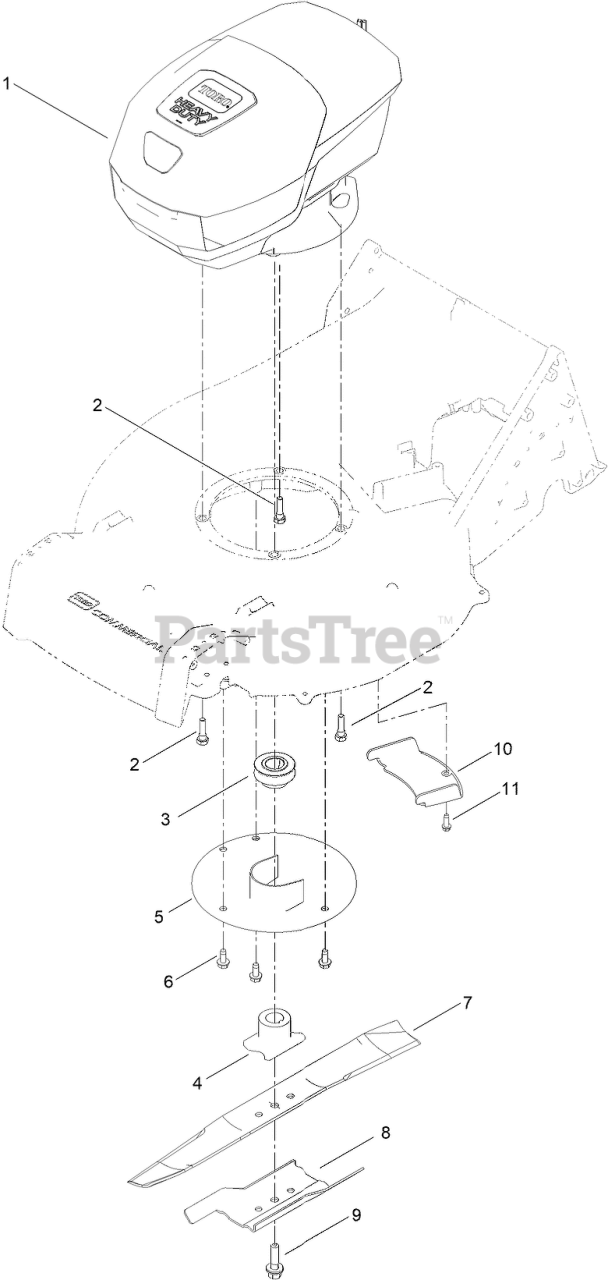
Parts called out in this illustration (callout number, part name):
1	MOTOR MODULE
2	SCREW-TAPTITE
3	PULLEY-DRIVER
4	DRIVER-BLADE
5	PROTECTOR-CRANKSHAFT
6	SCREW-HWHTF
7	BLADE-21IN, RECYCLING
8	ACCELERATOR-BLADE
9	BOLT-BLADE
10	COVER-BELT
11	SCREW-HWHTF
